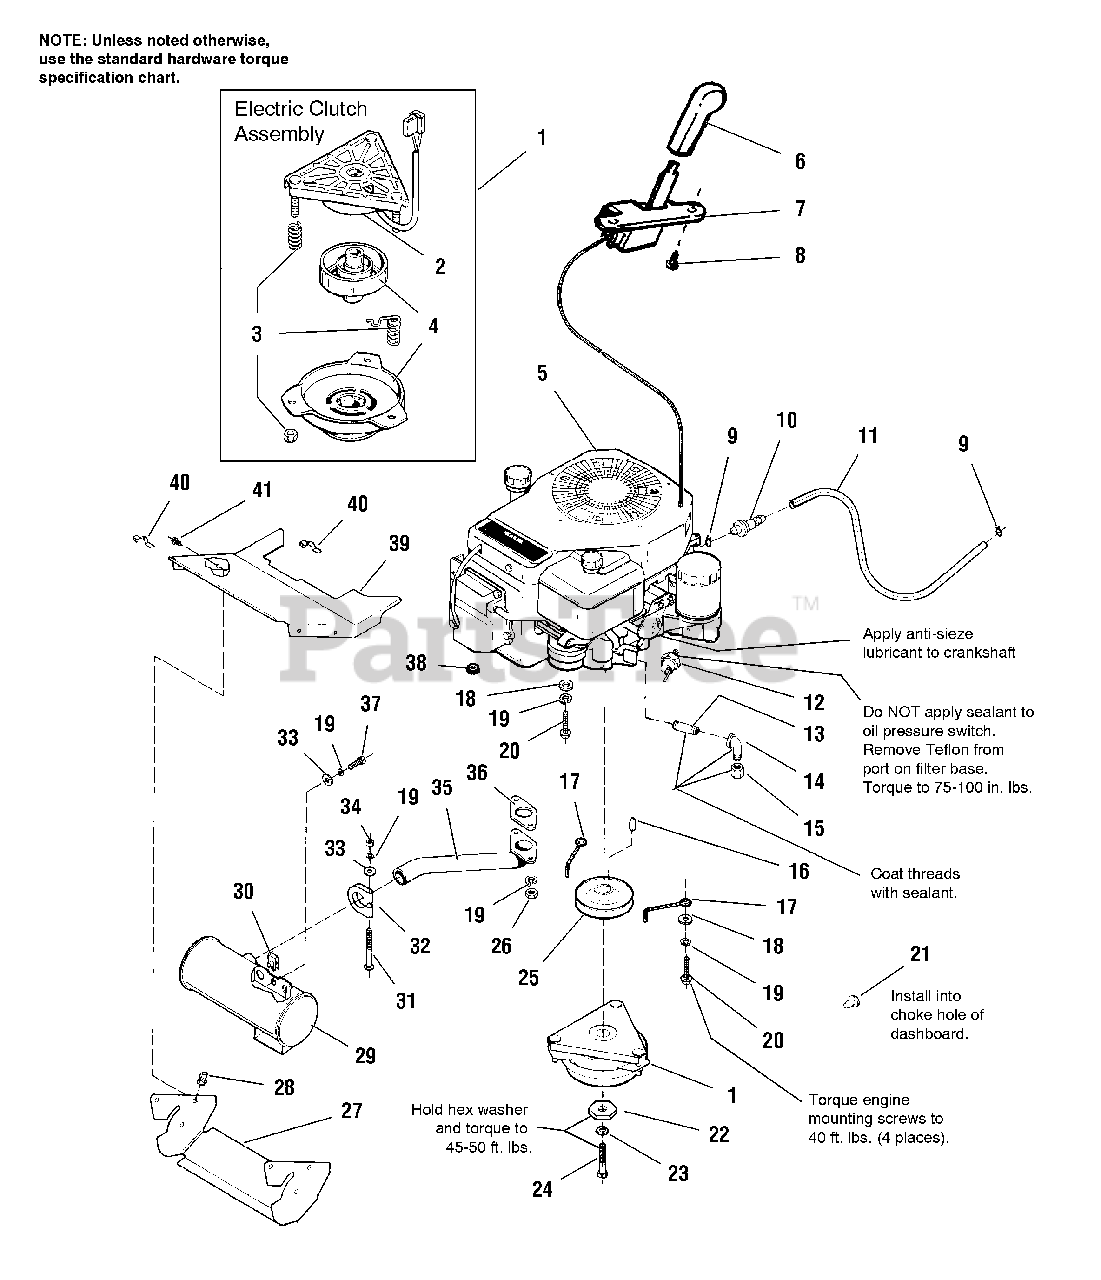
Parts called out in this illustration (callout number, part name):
1	ELECTRIC CLUTCH
2	FIELD ASSY., Clutch
3	SPRING & NUT KIT
4	ROTOR & ARMATURE ASSEMBLY
5	ENGINE, 15HP Kohler Command
6	KNOB, Throttle
7	THROTTLE CONTROL ASSY.
8	SCREW, Hex, Washer Hd., Plastite, 1/4-20 x 1/2
9	CLAMP, Hose
10	FUEL FILTER
11	HOSE, Fuel, 45-1/2" Long
12	SWITCH, Oil Pressure
13	PIPE NIPPLE, 3/8 x 2
14	STREET ELBOW, 3/8 Pipe
16	KEY, Hi-Pro
18	WASHER, Plain, 5/16
19	LOCKWASHER, 5/16
20	SCREW, Taptite, M8-1-1/4 x 30mm
21	FASTENER, Panel
22	WASHER, Hex
23	LOCKWASHER, 7/16
24	CAPSCREW, 7/16-20 x 2.5
25	PULLEY ASSY.
26	NUT, Exhaust
27	DUCT, Lower Muffler
28	PAL NUT, 1/4-20
29	MUFFLER ASSY.
30	PAL NUT, 5/16-18
31	CARRIAGE BOLT, 5/16-18 x 2-3/4
32	CLAMP, Muffler
33	WASHER, Plain, 5/16
34	NUT, Full, Hex, 5/16-18
35	PIPE, Exhaust
36	GASKET, Exhaust
37	CAPSCREW, Hex, 5/16-18 x 1
38	LOCKWASHER, External Tooth, 5/16
39	DUCT, Top, Muffler
40	CLIP
41	SCREW, Flange, Whizlock, 1/4-20 x 5/8
